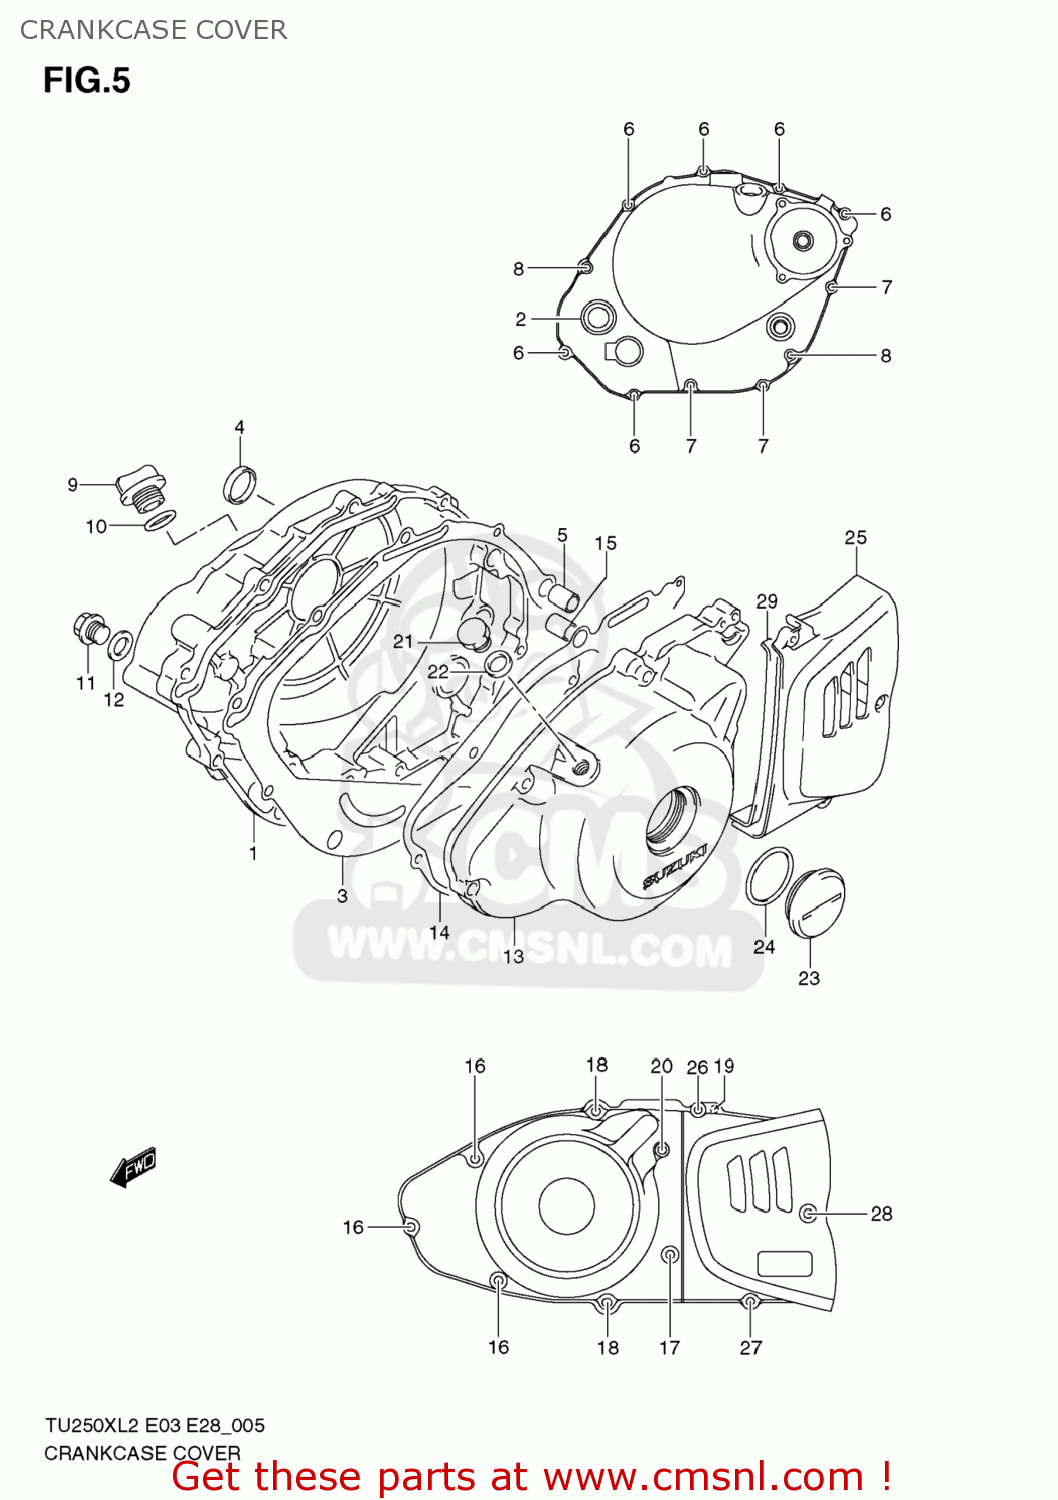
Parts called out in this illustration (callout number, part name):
1	COVER,CLUTCH
2	LENS,OIL LEVEL CHECK
3	GASKET,CLUTCH COVER (NAS)
4	PLUG,CLUTCH COVER KICK
5	PIN
6	BOLT(6X25)
7	BOLT(6X35)
8	BOLT(6X45)
9	PLUG,ENGINE OIL FILLER
10	O RING(D:3.1,ID:16.8)
11	PLUG(14X12)
12	GASKET(13.8X18.8X4.8) (NAS)
13	COVER,MAGNETO
14	GASKET,MAGNETO COVER (NAS)
15	PIN
16	BOLT(6X25)
17	BOLT(6X35)
18	BOLT(6X50)
19	BOLT
20	BOLT(6X60)
21	PLUG,12X9
22	GASKET(12.1X16.2X3.7) (NAS)
23	PLUG,36X10
24	O RING(D:3.1,ID:32.7)
25	COVER,ENGINE SPROCKET
26	BOLT(5X20)
27	BOLT(5X30)
28	BOLT(5X45)
29	DAMPER,ENGINE SPROCKET COVER
